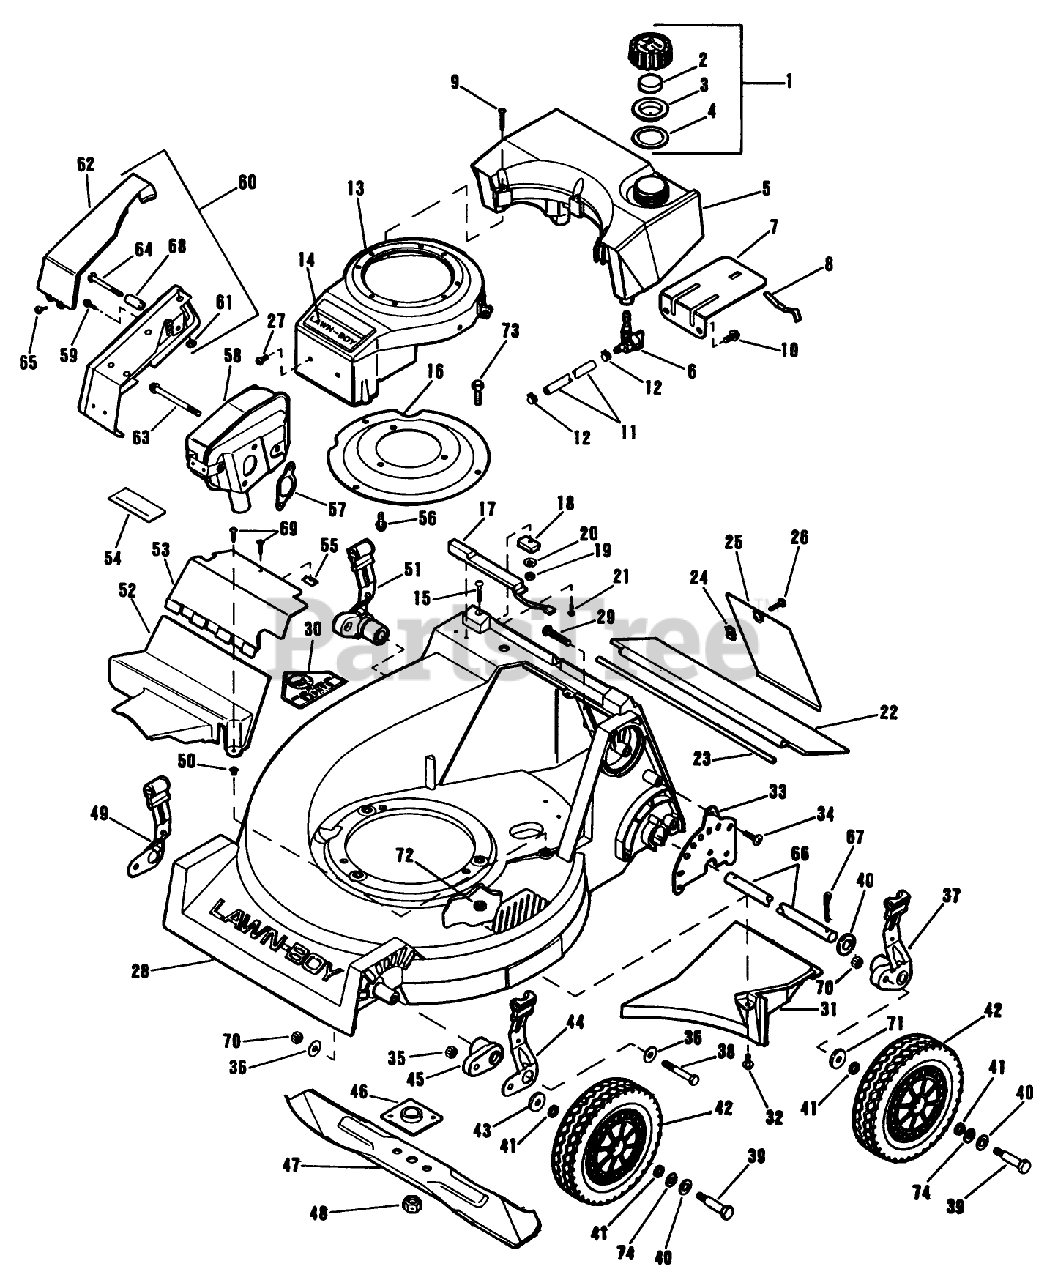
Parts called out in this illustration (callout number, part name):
1	CAP AY - F/OIL SM
2	BAFFLE - FOAM SM
4	GASKET-FUELCAP SM
6	DISC/LB SER.BUL.#6
7	DISC. LB SER.BUL.#6
8	SPRING
9	DISC.LB SER.BUL.#6
11	GAS LINE SM
12	HOSE CLAMP SM
14	APPLIQUE SM
17	Switch Assembly-Bag Lock
24	SPEED NUT LARSON
25	DOOR-ACCESS ELECT.
26	SCREW-CROSS RECESS
31	CHUTE BAFFLE NYL
33	PLATE HGT CMS
34	SCREW-BHTF
36	WASHER-PLAIN
37	HT. ADJ. ARM AY-L
39	BOLT WHEEL QUAL
40	SPACER
41	WASHER
42	WHEEL&TIRE 8" TRI
43	WASHER
44	KNOB & SPRING CMS
45	ARM HGT ADJ *BLACK
46	PLATE AND COLLAR ASM
48	NUT-BLADE
49	KNOB & SPRING CMS
50	NUT-CLIP
51	HT. ADJ. ARM AY-R
55	NUT-SPEED
57	GASKET - EXH SM
59	SCREW S
60	MUFFLER GUARD AY
61	NUT-PUSH
62	COVER MUFFLER CP
63	SCREW-SEMS
64	SCREW SM
65	SCREW SM
66	ROD HGT ADJ R GLM
68	SPACER S
69	SCREW S
70	LOCKNUT
71	WASHER WROUGHT
72	NUT-LOCK F
73	SCREW-HH
74	WASHER
